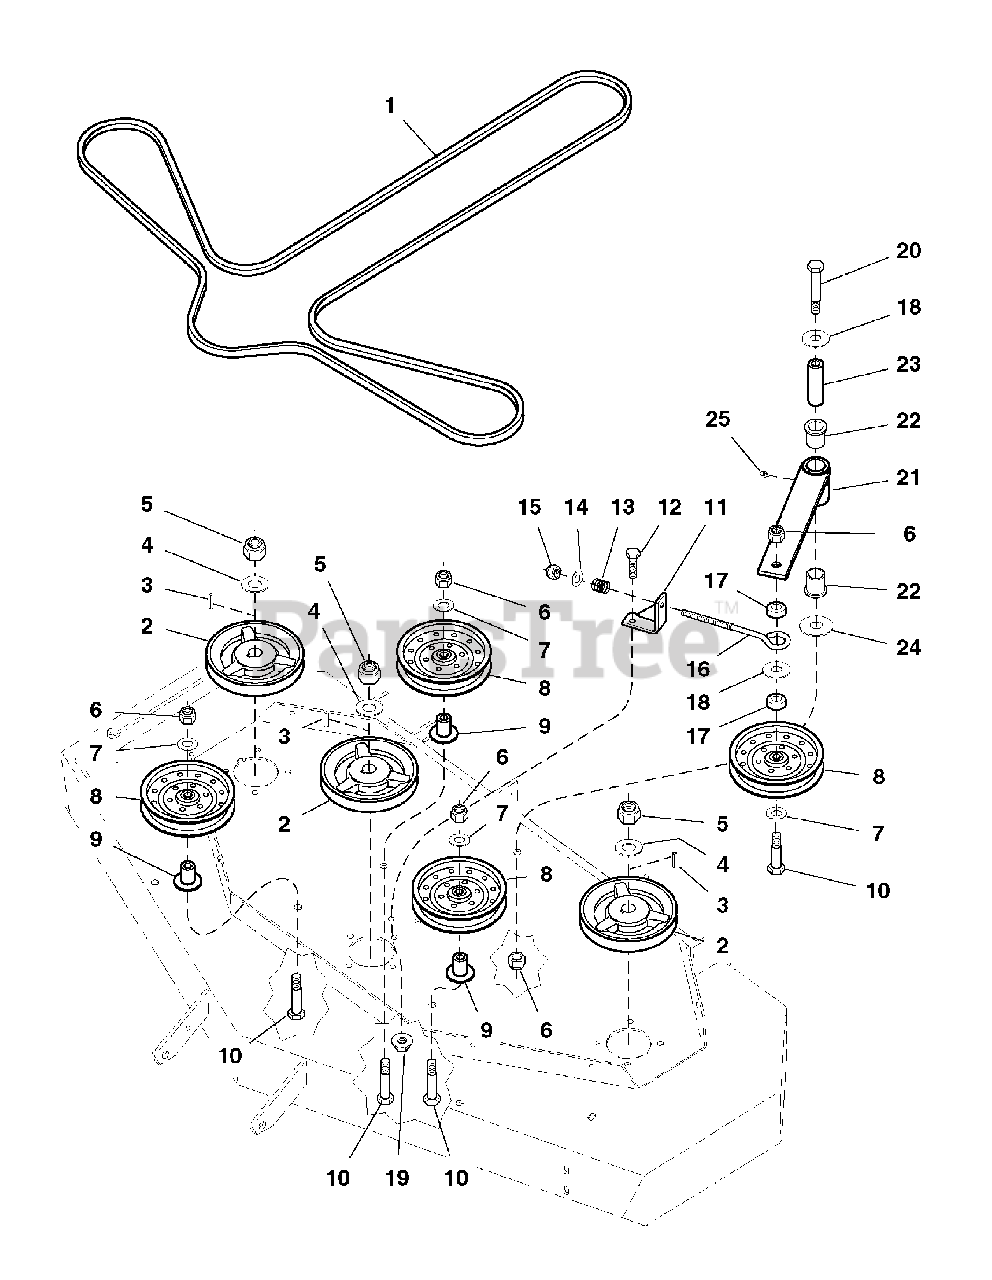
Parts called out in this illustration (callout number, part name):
1	BELT, 5V, 175.90EL, LG ARAMID, WRPD, RC
2	SPINDLE PULLEY
3	KEY, 1/4 x 1-1/4
4	WASHER, Spring
5	NUT, Hex, Nylon Lock, 5/8-18
6	NUT, Hex, Nylon Lock, 1/2-13
7	WASHER, 1/2
8	*PULLEY, FLAT IDLER, 6-3/4"
9	IDLER PULLEY MOUNT
10	CAPSCREW, Hex Hd, 1/2-13 x 3
11	SPRING ANCHOR
12	CAPSCREW, Hex Hd, 3/8-16 x 1
13	SPRING, Compression
14	WASHER, 3/8
15	NUT, Hex, Nylon Lock, 3/8-16
17	IDLER SPACER
18	WASHER, USS, 1/2
19	NUT, Hex, Serrated Flange, 3/8-16
20	CAPSCREW, Hex Hd, 1/2-13 x 4-1/2
21	IDLER ARM
22	BUSHING, Flange
23	IDLER ARM PIVOT SHAFT
24	WASHER, 5/8
25	GREASE FITTING
